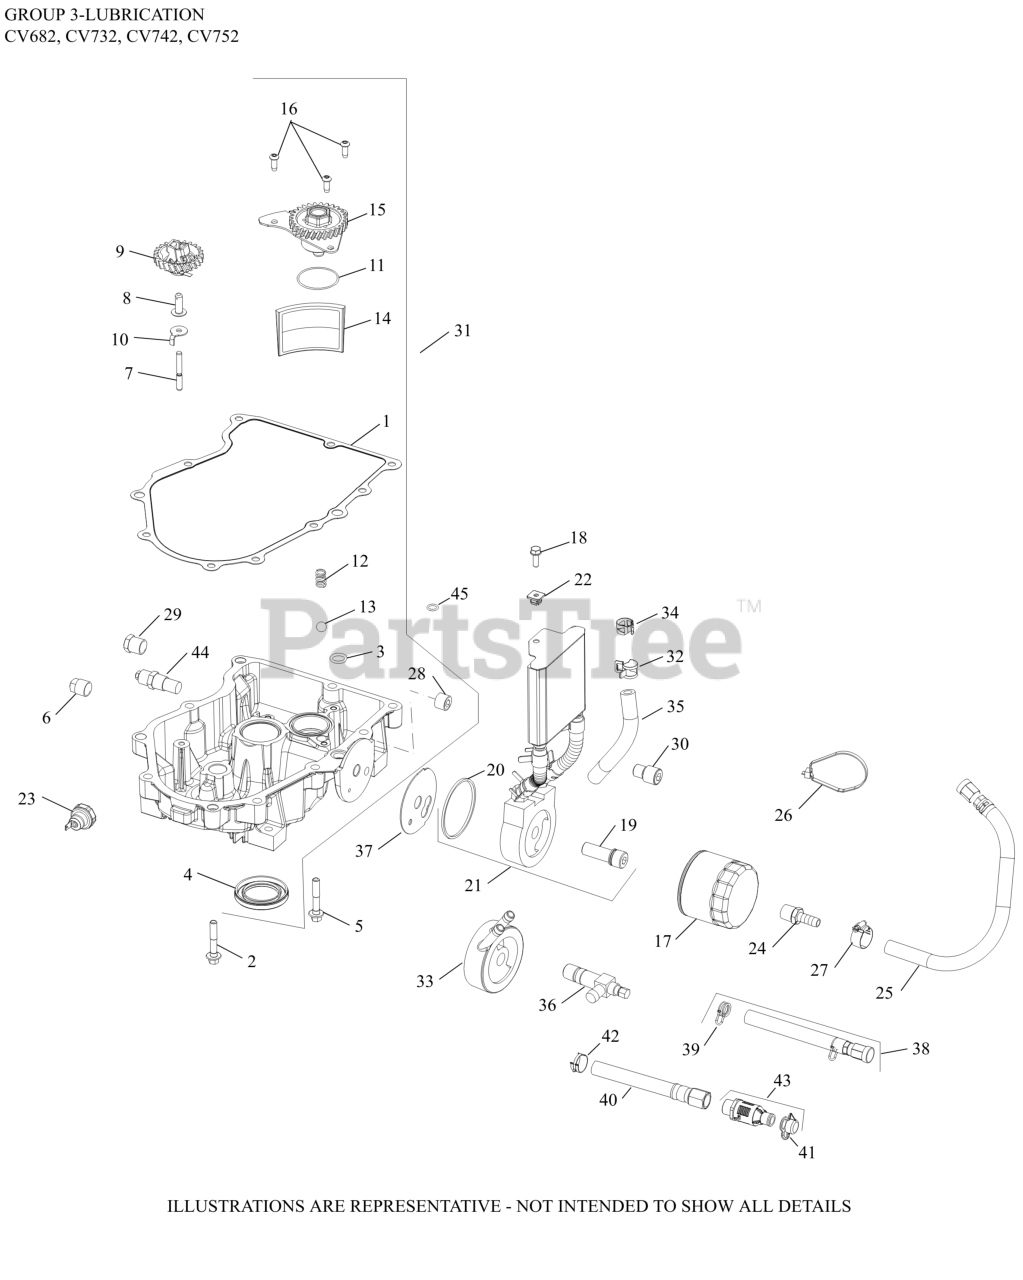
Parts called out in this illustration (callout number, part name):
1	GASKET, OIL PAN
2	SCREW, FLG M8X1.25X45
5	SCREW, HEX FLANGE
6	PLUG, SQ HD PIPE 3/8"
7	SHAFT, GOVERNOR GEAR
8	PIN, GOVERNOR REGULATING
9	KIT, GOVERNOR GEAR W/PIN
10	TAB, LOCKING
11	O-RING (1.78" DIA)
12	SPRING, COMPRESSION
13	PRESSURE RELIEF BALL
14	SCREEN, OIL
15	PUMP, OIL ASSEMBLY
16	SCREW, BUTTON HEAD
17	OIL FILTER
18	SCREW, TAPPING
19	NIPPLE, OIL FILTER - (#2413608S)
20	O-RING, OIL COOLER
21	COOLER, OIL & DIVERTER ASSEMBLY
22	NUT, PLASTIC - BLACK
28	PLUG, PIPE CTSK 3/8"
31	KIT, OIL PAN ASSEMBLY
31	PAN, ASSEMBLY OIL (SERVICE)
33	ADAPTER, OIL FILTER (CV EFI)
34	CLAMP, HOSE LOW PROFILE
35	KIT, HOSE 140MM
